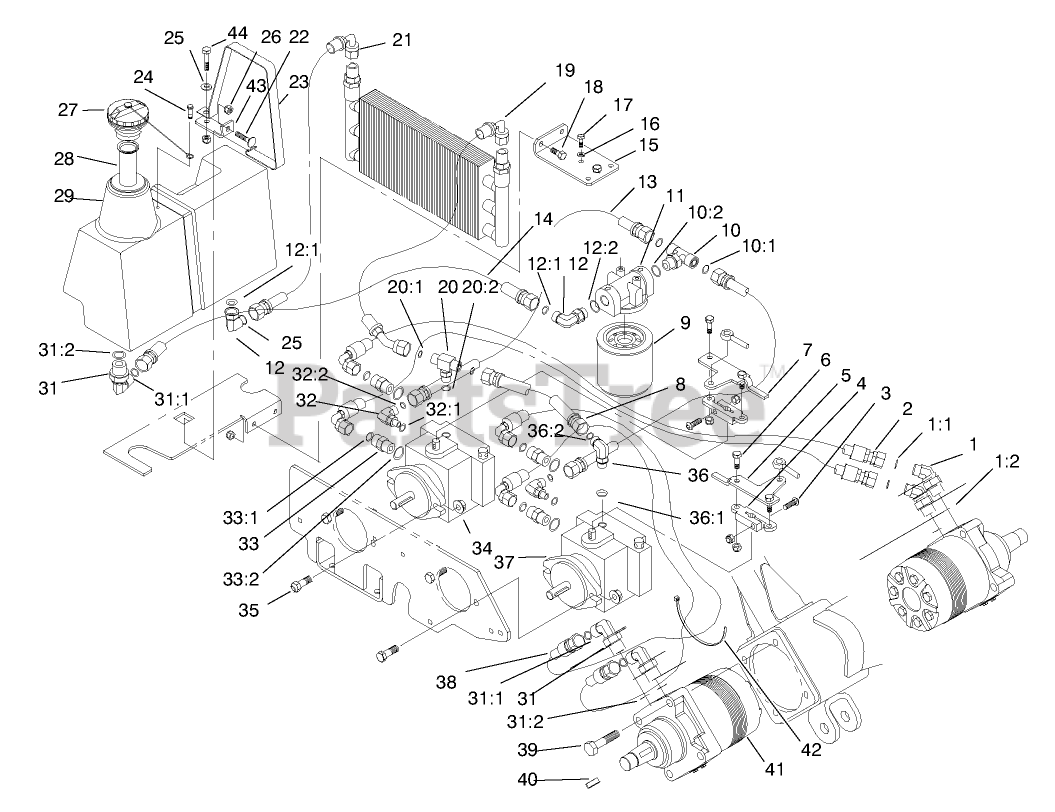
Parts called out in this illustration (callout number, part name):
1	FITTING-HYD, 45 DEG
1:1	O-RING
1:2	O-RING
2	HOSE-HYDRAULIC
3	SCREW-HSH
4	ARM-CONTROL, PUMP
5	PLATE-CONTROL, LEFT
6	SCREW-HH
7	PLATE-CONTROL, RIGHT
8	HOSE-HYD
9	CARTRIDGE-FILTER, OIL
10	FITTING-HYD, TEE
10:1	O-RING
10:2	O-RING
11	HEAD-FILTER
12	FITTING-ELBOW-90 DEG
12:1	O-RING
12:2	O-RING
13	ASM - HOSE,HYDRAULIC
14	HYDRAULIC HOSE ASM
15	ANGLE-MOUNT, HYD FILTER
16	WASHER-LOCK
17	SCREW-HH
18	SCREW-HH
19	HYDRAULIC HOSE ASM
20	ADAPTER
20:1	O-RING
20:2	O-RING
21	HYDRAULIC HOSE ASM
22	BOLT-CARR
23	STRAP-TANK, HYD
24	SCREW-SHOULDER
25	WASHER-PLAIN
26	NUT-LOCK, NI
27	CAP-OIL
28	FILTER-SCREEN
29	TANK-HYD
31	FITTING-ELBOW 90
31:1	O-RING
31:2	O-RING
32	FITTING-ELBOW 90
32:1	O-RING
32:2	O-RING
33	FITTING-STRAIGHT
33:1	O-RING
33:2	O-RING
34	NUT-HF
35	SCREW-HH
36	FITTING-ELBOW, 90 DEG
36:1	O-RING
36:2	O-RING
37	HYDRAULIC PUMP
38	HYDRAULIC HOSE ASM
39	SCREW-HH
40	KEY-WOODRUFF
41	MOTOR - HYDRAULIC WHEEL
42	TIE-CABLE
43	Mount-Strap
44	SCREW-HH
45	SEAL KIT
